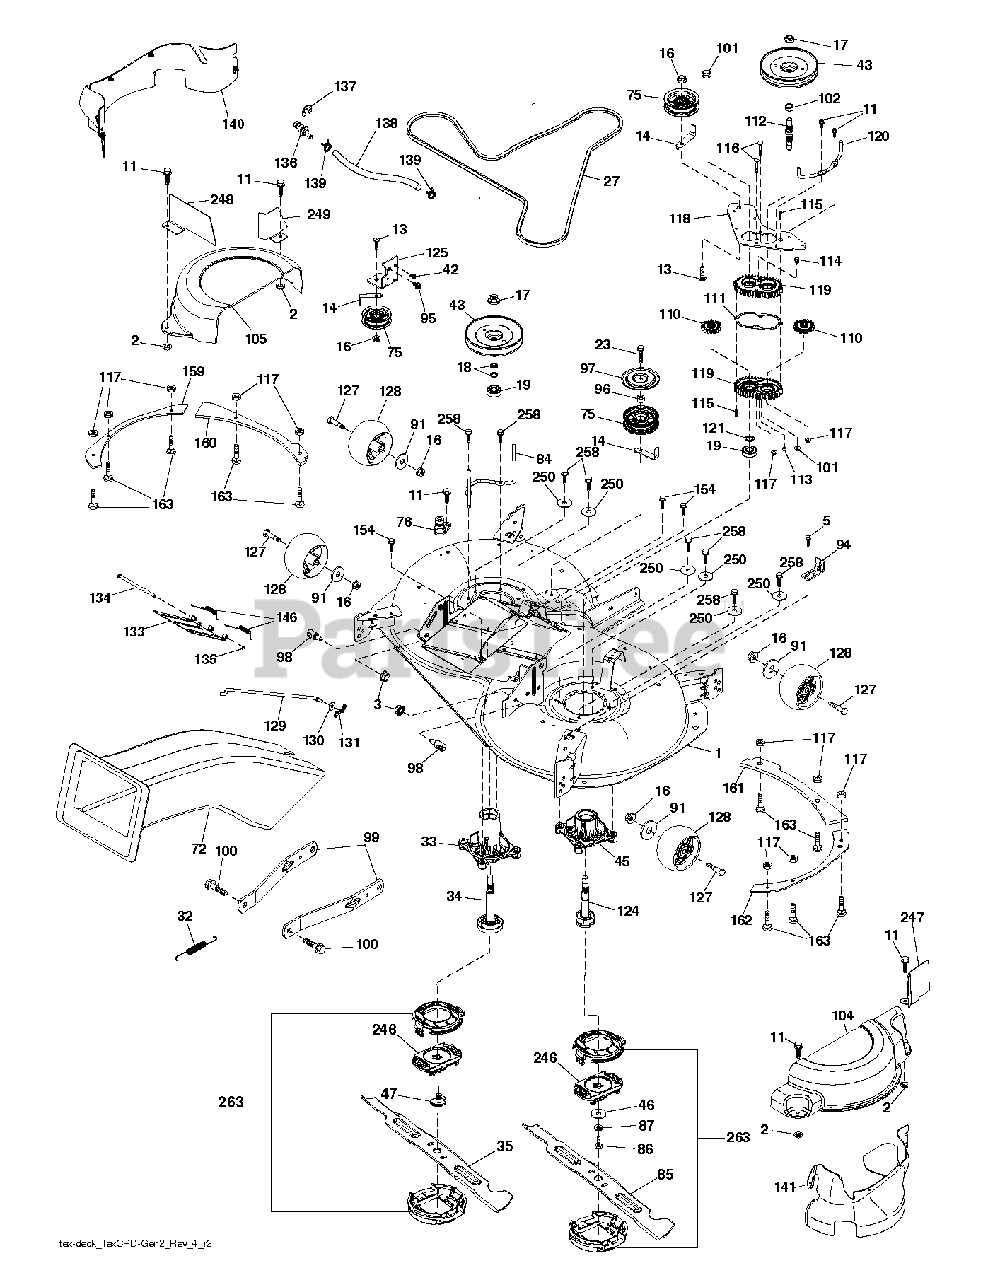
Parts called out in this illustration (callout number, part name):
1	DECK SVC 107HP.EZMUL.498
2	PALNUT 1/4
3	NUT LOCK HEX FLANGE 5/16-18
5	BOLT.5/16HEX.WHS.HD
11	SCREW.1/4-20X5/8
13	BOLT.3/8-16X1.50
14	KEEPER, BELT IDLER
16	NUT LOCK FLG 3/8-16 UNC
17	NUT.FLANGE.LOCK.TOP
18	WASHER.SPACER.MANDREL
23	SCREW LT
27	BELT BELT. ELECTRIC MOWER DRIV
32	SPRING 107CM & 97CM ELECTRIC D
33	HOUSING.MANDREL.REV.TALL.N/GRS
34	SHAFT ASM.REV.TALL.N/GREASEBL
35	BLADE.REVLTION.107CM.LHS.PT431
42	SCREW
43	PULLEY PULLEY MANDREL 5.438 PD
45	RP HOUSING.MANDREL.REV.REVS.
46	3/8 FLAT WASHER
47	SCREW.SEMS.7/16-20X1.HEX.HEAD
72	RB CHUTE 107/97 TEX GENII
75	FLAT IDLER PULLEY
76	1/2" BARB.DECK.WASHOUT.PORT
84	KEEPER KEEPER. LH MANDREL BELT
85	BLADE.REVLTION.107CM.RHS.PT431
86	BOLT.3/8-24X1.25GR8. LHTHRD
87	LOCKWASHER
91	WASHER
94	BRKT.CLUTCH.CABLE
95	SCREW, 3/8-16X3/4
96	SPACER
97	PROTECTOR
98	STUD.FASTNER.W/ANTI-ROTATE
99	ARM.SUSPENSION.MOWER.R
100	BOLT.SHOULDER
101	NUT.CROWNLOCK.9/16 -18.UNC
102	SPACER BEARING
104	COVER.MANDREL.107.RH.GEN.2
105	COVER.MANDREL.107.LH.GEN.2
110	GEAR GEAR OUTPUT
111	GASKET GASKET GEARCASE
112	SHAFT SHAFT. CRD GEARCASE ADAP
113	PLUG PLUG OIL
114	VALVE VALVE RELIEF
115	SCREW
116	BOLT.CARIGE.SS.1/4-20X1.75GR5
117	NUT T
118	ARM ARM. CLUTCHING 107 TEX CRD
119	GEARCASE GEARCASE SUBASM
120	KEEPER KEEPER. RH MANDREL BELT
121	WASHER WASHER
124	SUB.ASM.REVERSE.THREAD.REV
125	BRACKET
127	BOLT.SHOULDER.3/8-16X3-5/8.
128	WHEEL. GUAGE RALLY
129	ROD ROD. SWAY CRD GEN II
130	WASHER
131	PIN.COTTER.5/16.BOW TI
133	COVER DOOR.107 CM CRD EZ MULCH
134	PIN PIN.HINGE
135	E-RING.5/16"
136	PLUG WASHOUT PORT HOOKUP
138	107.WASHOUT.PORT.HOSE (2 2)
139	HOSE.3/8.CLAMP (2 2)
140	GUARD FRENCH 107 TEX ASSEMBLY
141	GUARD SUBASM. 107 TEX GEN 2 RH
146	SPRING SPRING: EZ MULCH DOOR
154	SCREW T-30 1/4-20 X
159	REINFORCE.PLATE.LH.FT.X431
160	REINFORCE.PLATE.LHS.BOLT.431
161	REINFORCE.PLATE.RH.FRT.X431
162	REINFORCE.PLAT.RH.SD.BLT.X431
163	BOLT
246	HOLDER.BLADE.REVOLUTION
247	GUARD.STEEL.CRD.MANDREL.COV.FR
248	GUARD.STEEL.CRD.MANDREL.COV.FR
249	GUARD.STEEL.CRD.MANDREL.COV.FR
258	BOLT.HEX.WASHR.HED.313-18X1.19
263	CAP.REVOLUTION ASM
